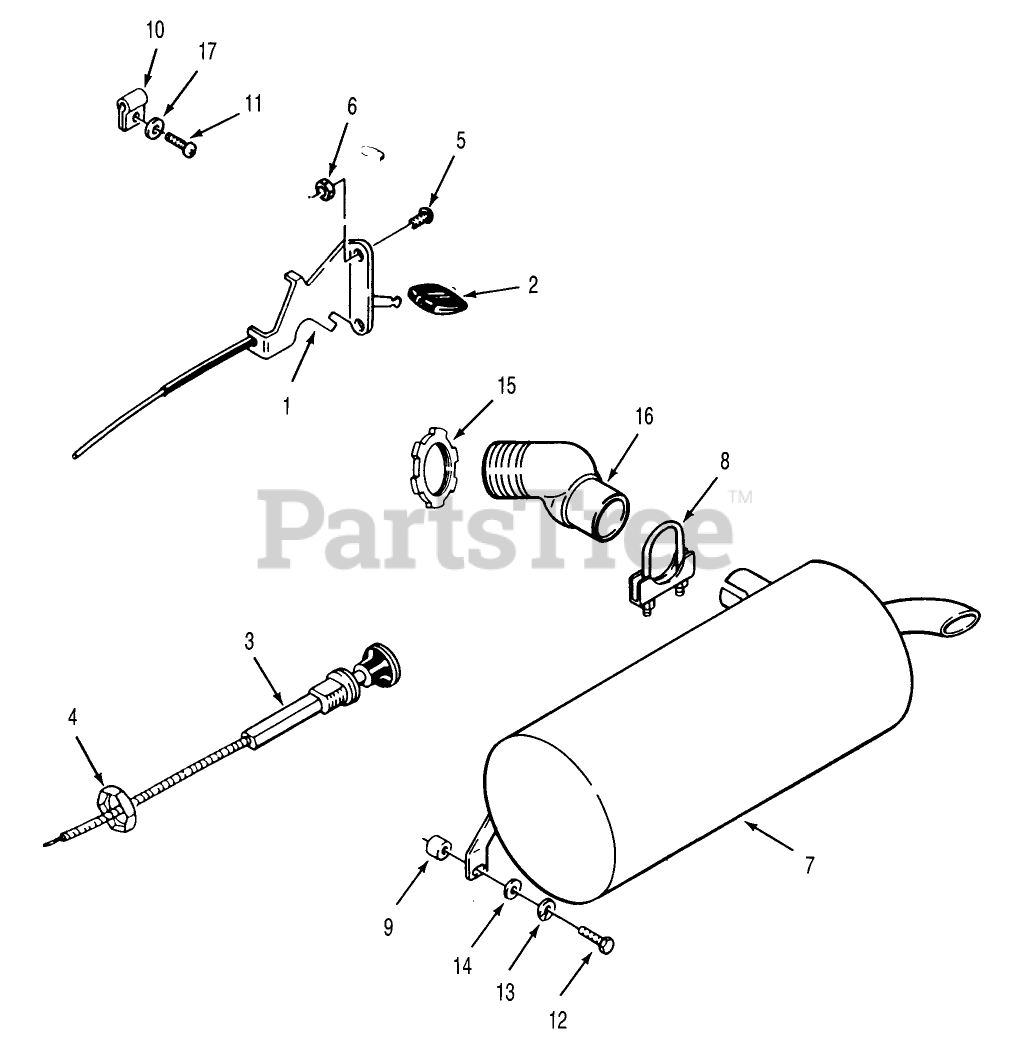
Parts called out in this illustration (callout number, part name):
1	CONTROL-THROTTLE
3	CONTROL CHOKE
4	NUT-HEX PALNUT
5	SCREW-PPH
9	SPACER
10	KOHLER 48-154-01
11	KOHLER X-67-83
14	WASHER 5/16 SAE
15	KOHLER AC-1536
16	KOHLER47-054-01
17	KOHLER X-25-72
